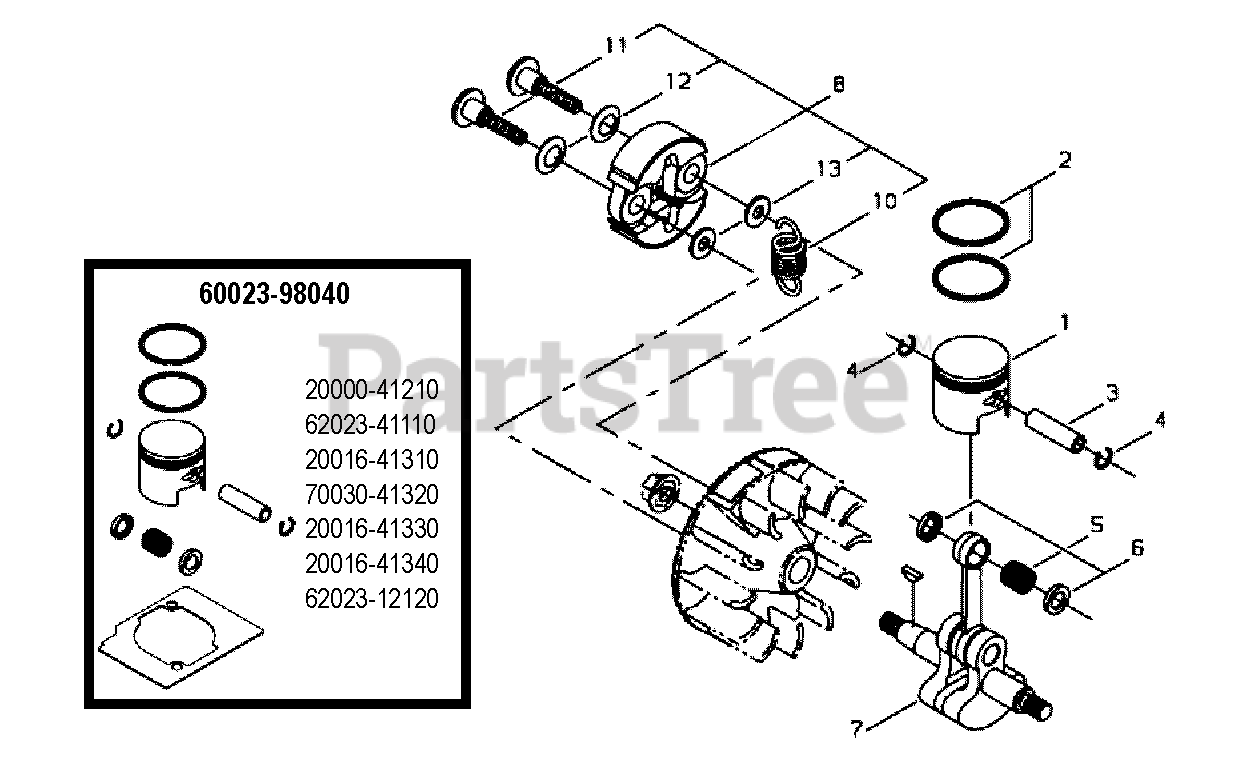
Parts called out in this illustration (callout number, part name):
1	PISTON
2	RING, PISTON
3	PIN, PISTON
4	RING, RETAINING
5	BEARING, NEEDLE
6	WASHER, THRUST
7	CRANKSHAFT ASSY
8	CLUTCH ASSY
10	SPRING, CLUTCH
11	BOLT, CLUTCH
12	WASHER - SPRING
13	WASHER - 6
